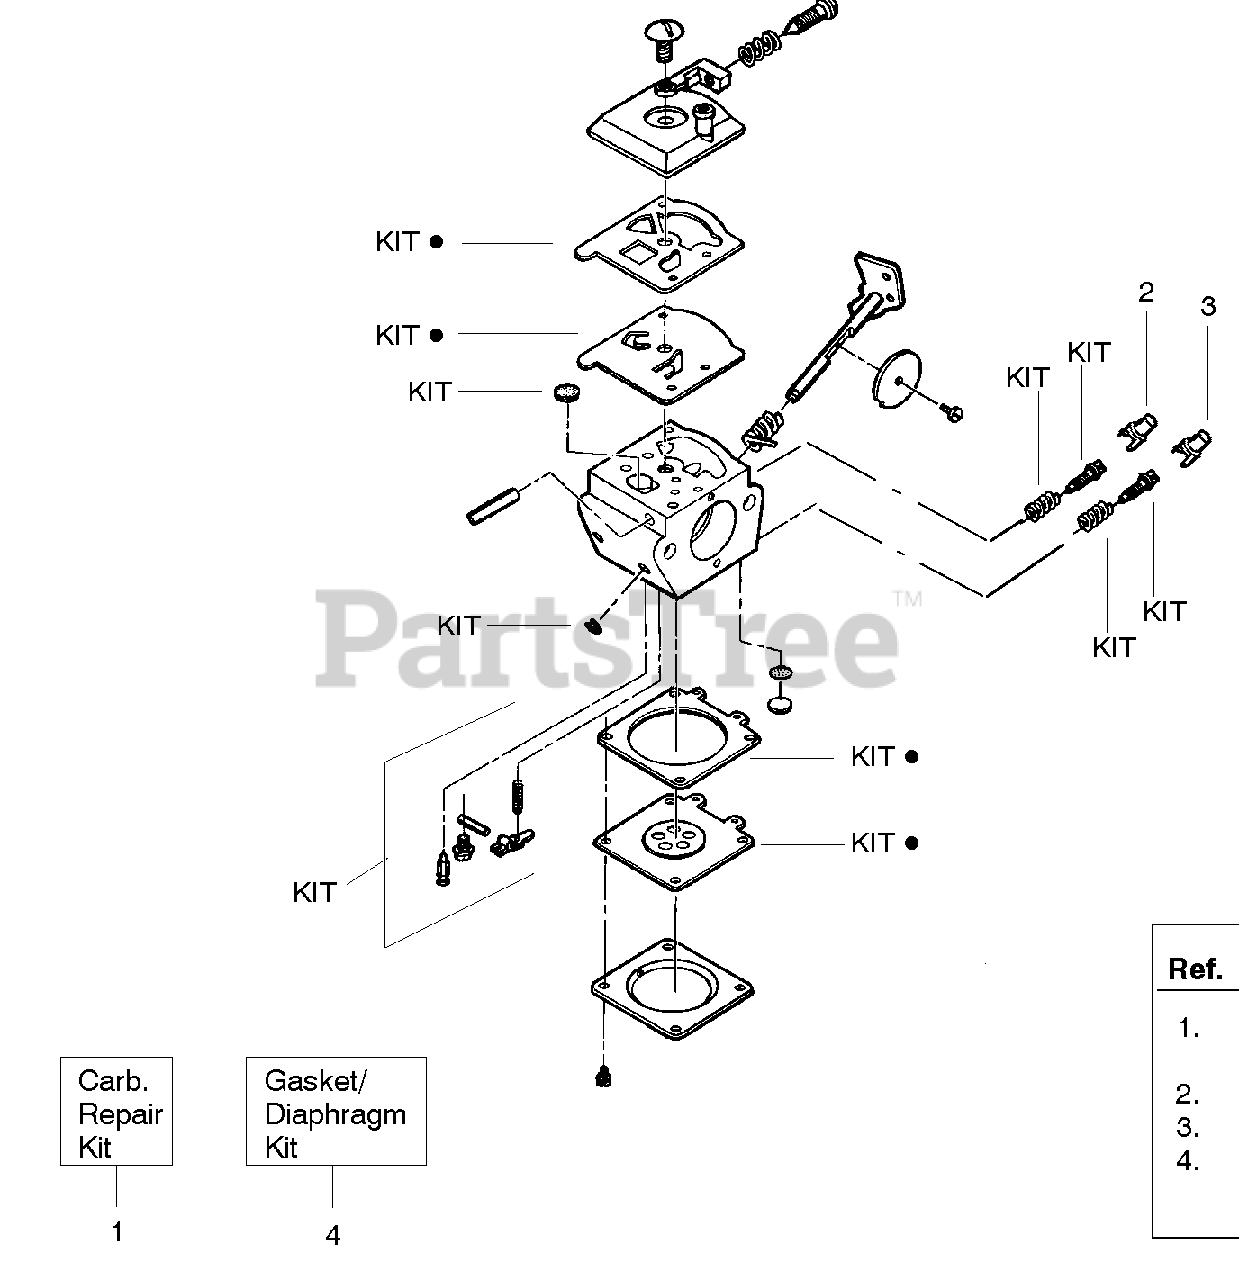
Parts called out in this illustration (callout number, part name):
1	Carburetor Repair Kit (KIT= Indicates Contents)
2	Limiter Cap (High-brown)
3	Limiter Cap (Low-tan)
4	Gasket/Diaphragm Kit (• =Indicates Contents)
